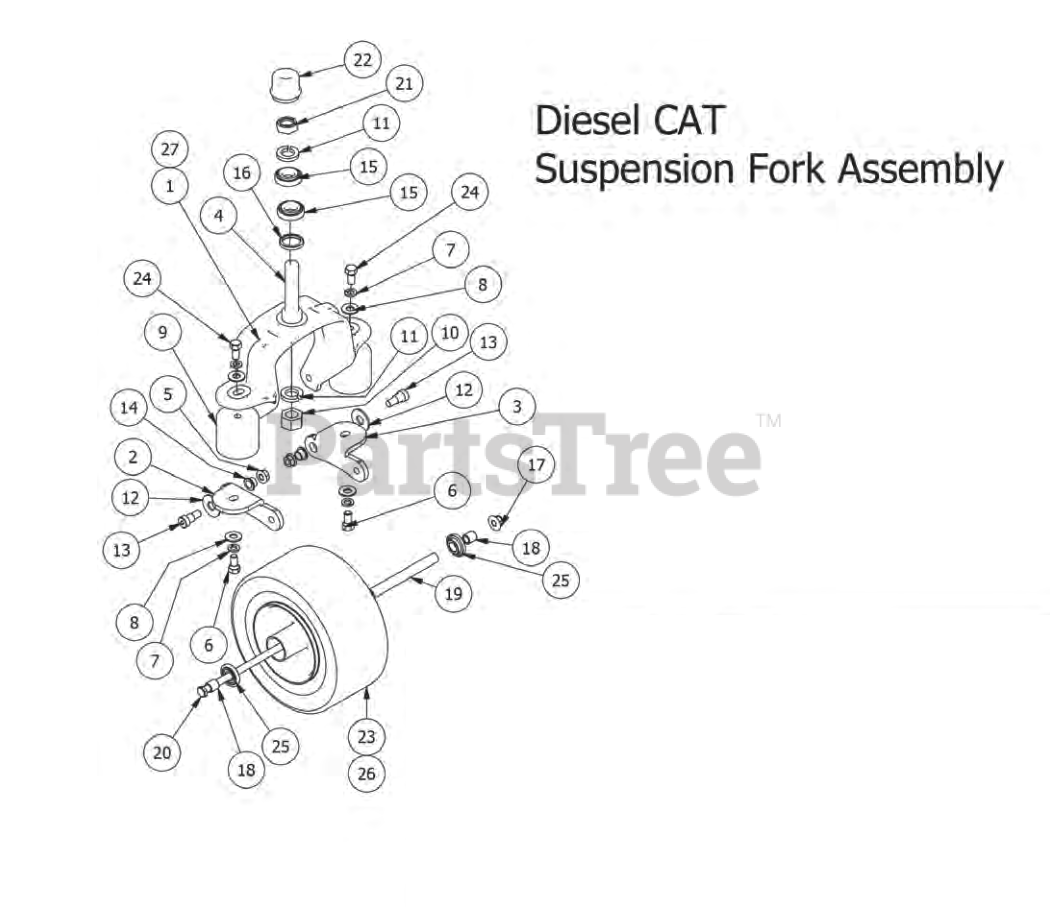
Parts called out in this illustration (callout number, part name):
1	Suspension Fork Top/Side Combo
2	Suspension Fork - Bottom Left
3	Suspension Fork - Bottom Right
4	Front Suspension Fork Spindle
5	1/2" Flange Nut
6	1/2" x 1" Hex Bolt
7	1/2" Lock Washer
8	1/2" Washer (Grade 8)
9	Vibration Mount- Red Dot
10	1" Fine Thread Nut
11	1" Lock Washer
12	5/8" Flat Washer
13	5/8" x 5/8" Shoulder Bolt
14	Bronze Bushing - SF-2024-8
17	1/2-13 Nylon Flange Nut-Orange
18	3/4 OD x 1/2 ID x 3\4 Length
19	Front Wheel Spanner
20	1/2" x 10" Bolt
21	1" Fine Thread 1/2 Nut
22	Dust Cover
23	13 x 6.50-No-Flat Large Bore Orange front Assembly
24	1/2" x 1-1/4" Gr5 Hex Bolt (Coarse)
25	1-3/4" Bearing-Large Bore Front Rim
26	13 x 6.50- Reliance No-Flat
27	Suspension Fork Assembly
